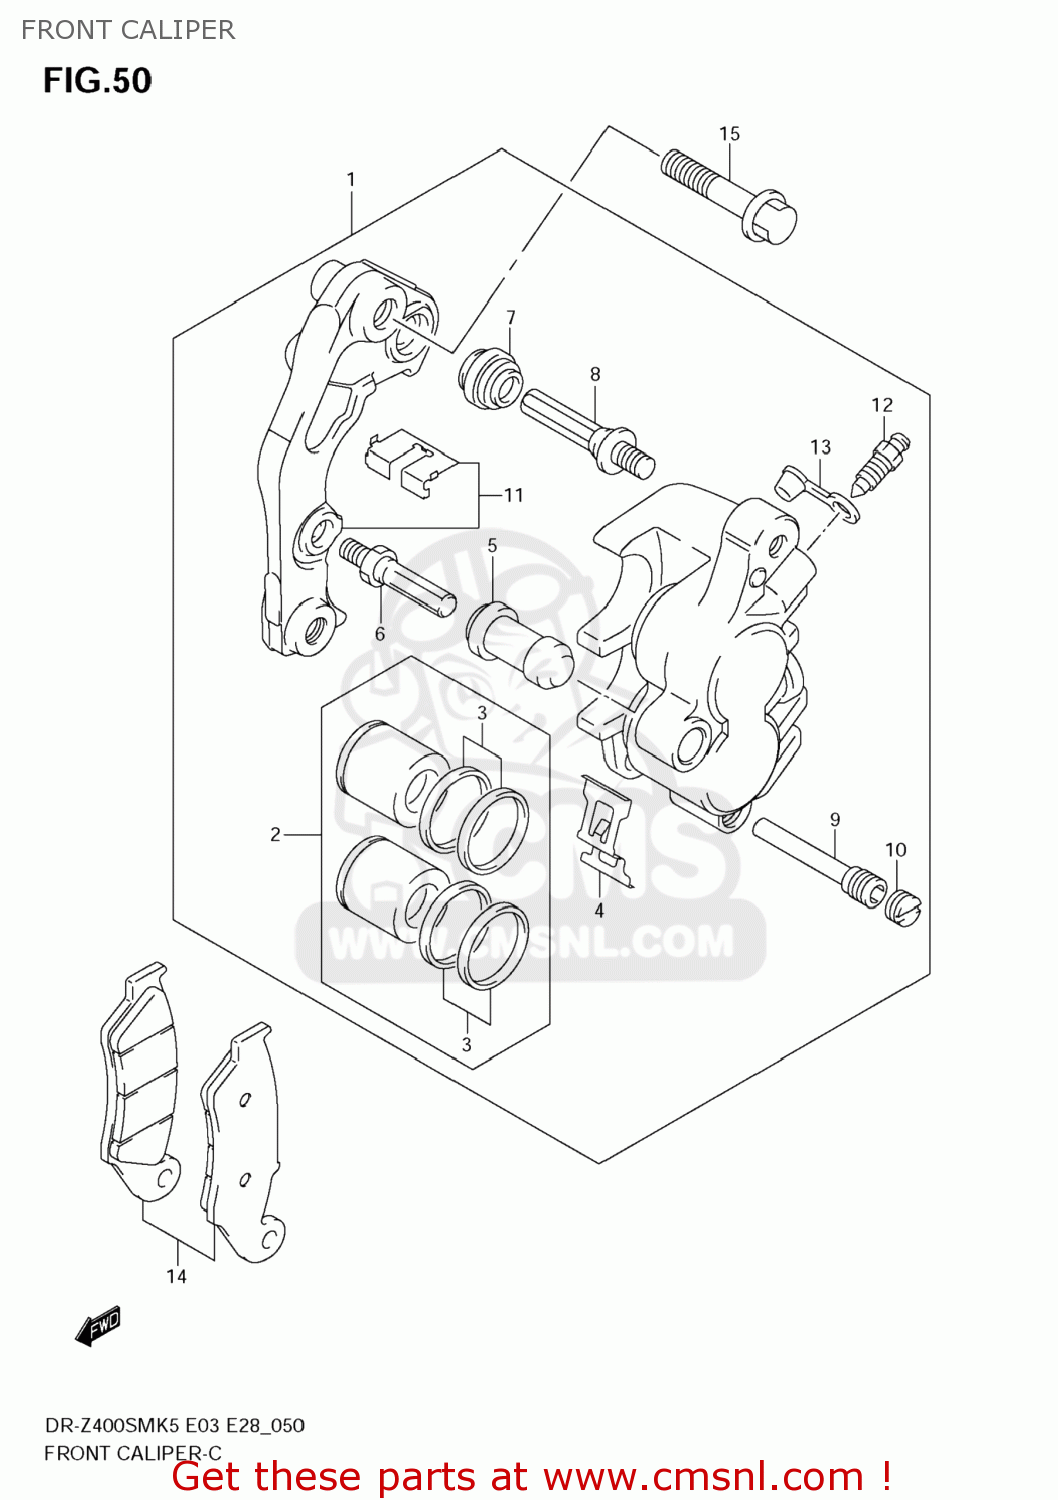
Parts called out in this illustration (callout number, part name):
1	CALIPER ASSY,F
2	PISTON SET
3	SEAL SET,PISTON
4	SPRING,PAD
5	BOOT
6	BOLT
7	BOOT
8	PIN
9	PIN,HANGER
10	PLUG,PIN
11	BRACKET
12	BLEEDER
13	CAP,BLEEDER
14	PAD SET (NAS)
15	BOLT(8X40)
